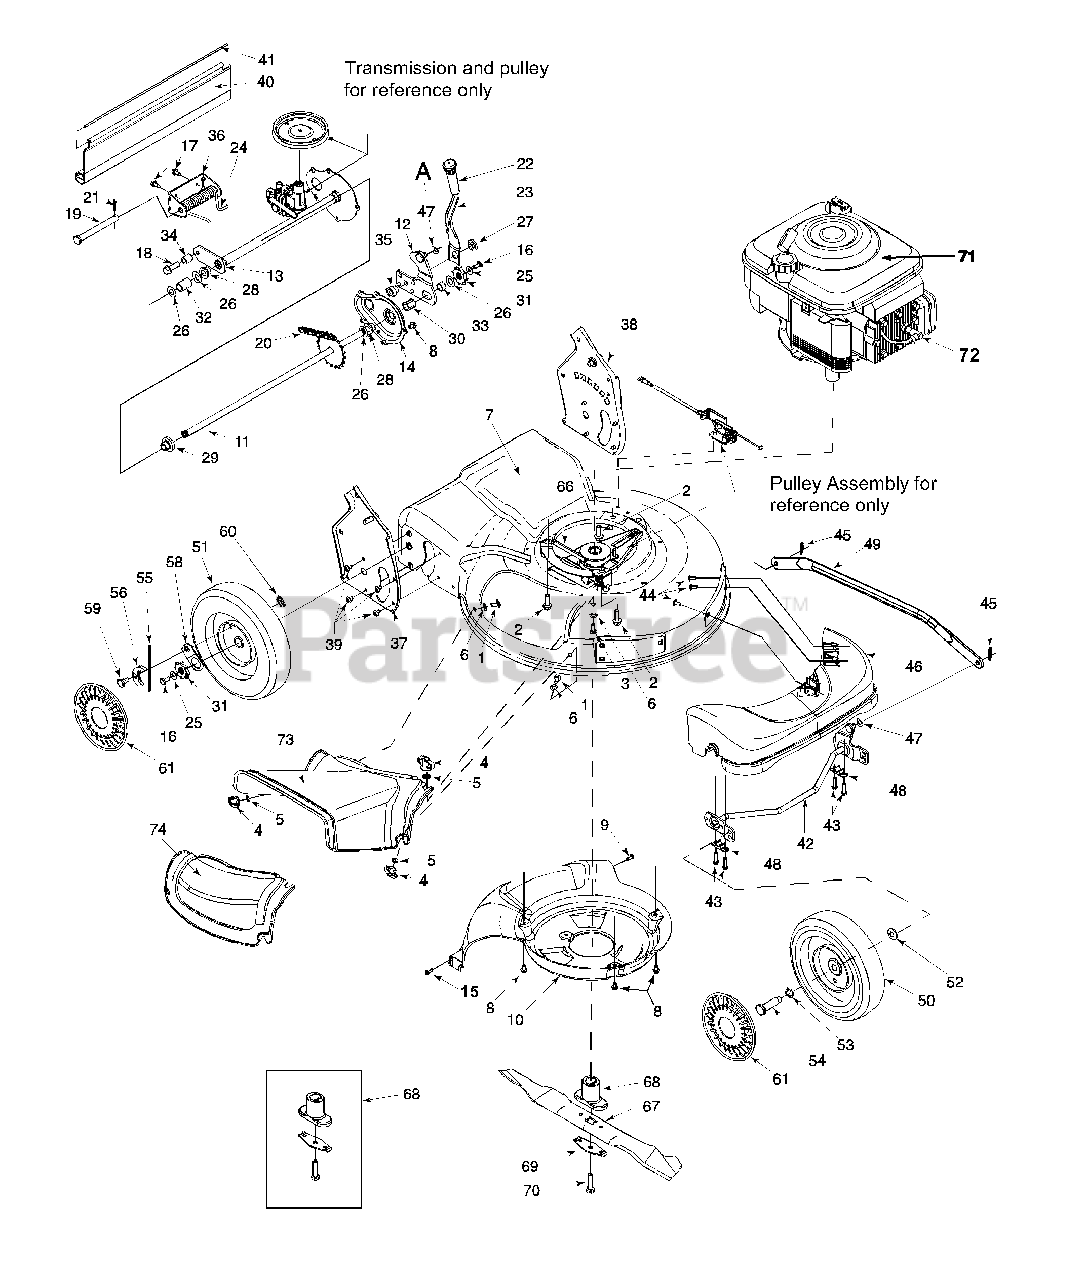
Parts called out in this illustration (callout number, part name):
1	Carriage Bolt 1/4-20 x .62
2	TT Screw: 3/8-18:1.00
3	Screw 1/4-20 x .750
4	Wing Nut 1/4-20
5	Nut, Push .25 I.D. x .50 O.D.
6	Wash. Fl. .334 I.D.x .62 x.03
8	TT Screw 1/4-20 x .375
10	Baffle
11	Rear Axle Ass'y
16	Cap Screw HH 1/4-20 x .620
17	AB Screw 1/4-14 x .825
18	Screw, 3/8 116 x .25
19	Clevis Pin .50 Dia. x 4.82 Lg.
20	Chain-Endls. #48 .500P x 24L
21	Cotter Pin .125O.D. x .75
24	Torsion Spring
27	Shoulder Nut .825 Dia. x .165 Lg.
28	Hx.Flg. Bearing
29	Hx.Flg. Bearing
30	Hx. Slv. Bearing
31	Wheel Rachet
32	Spacer
35	Shoulder Spacer
40	Trail Shield
41	Trail Shield Wire
43	Wash Hd. Hx Screw
44	Truss Torx Screw
45	Cotter Pin .072 x 1.12 Lg.
46	Front Axle Cover
47	Bowed Washer
48	Bush. Block .505 Dia. x .62
50	Wheel 8 x 2
51	Wheel 9 x 2
52	Spring Washer .401 x .870 x .o63
53	Wave Washer .510 x .750 x .017
54	Shoulder Screw
55	Ratchet Spring
58	Ratchet Pawl Plate
59	Hubcap - Gray
60	Top Lock Tab Weld Nut 1/4-20
61	Hubcap - Gray
66	Belt
67	21" Mulching Blade
68	Blade Adapter Kit
69	Blade Bell Support
70	Hex Bolt 3/8-24x2.5' Lg.
71	Engine
72	Spark Plug Insulator
73	Side Discharge Chute
74	Mulch Cover
